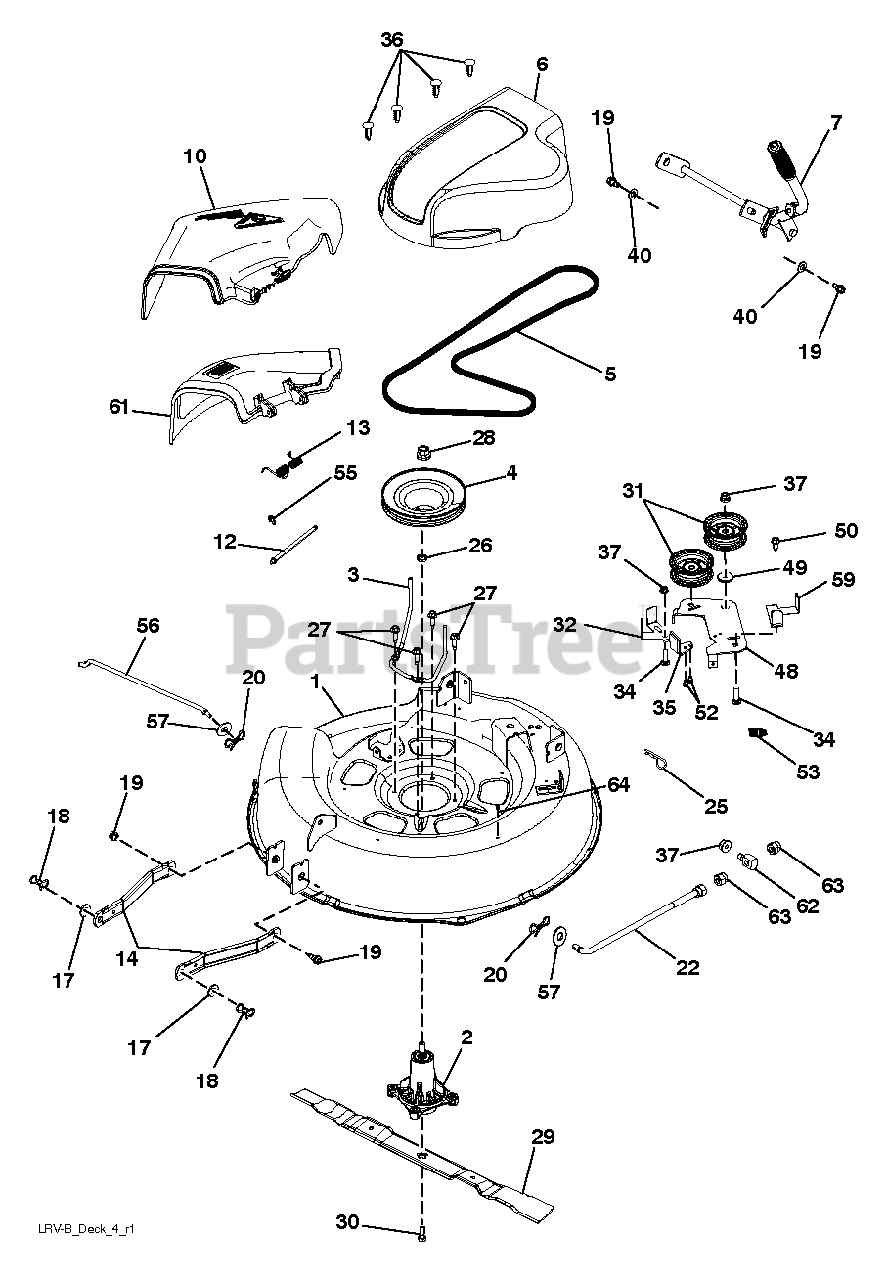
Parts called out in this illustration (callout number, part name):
1	DECK.WELDMENT.LRV.30.BLACK
2	MANDREL.ASM.SUB-NON.GR
3	KEEPER.LRV.GEN2.MANDREL BELT
4	PULLEY.LRV.GENS.MANDREL
5	V-BELT.MOWER.30.LRVB
6	COVER.MANDREL.30".LRV.(B)
7	LIFT.ASM.DECK.LRV
10	DEFLECTOR ASSEMBLY
12	PIN.HINGE
13	SPRING.DOUBLE.TORSION.SPRING
14	ARM.SUSPENSION.MOWER
17	WASHER.CLEAR.ZINC
18	PIN.COTTER.7/16.BOW TI.
19	BOLT.SHOULDER
20	PIN.COTTER.5/16.BOW TI
22	LINK.ASM.TOP.DECK.LRV
26	WASHER.SPACER.MANDREL
27	SCREW, WASHER HEAD
28	NUT.FLANGE.LOCK.TOP
29	BLADE, MULCH.LRV30
30	BOLT.WASHER.ASM.7/16-2
31	PULLEY.IDLER.48"PRIMARY
32	GUARD, BELT
34	BOLT.3/8-16X1.50
35	ARM BRAKE MOWER RH
36	SCREW.1/4-20X5/8
37	NUT LOCK FLG 3/8-16 UNC
48	ARM.LRV.GEN2.CLUTCHING
49	SPACER.RETAINER
50	SCREW 3/8-16X1
52	SCREW 1/4X20
53	SPRING RETURN
55	E-RING.5/16"
56	ROD.LRV.GEN2.ANTI.SWAY
57	WASHER
59	GUARD.TUV.IDLER.42
61	MULCH.COVER.ASSEMBLY.30"
62	TRUNNION
63	NUT, LIFT LINK 7/16-20
64	SCREW 3/8-16X1/2
